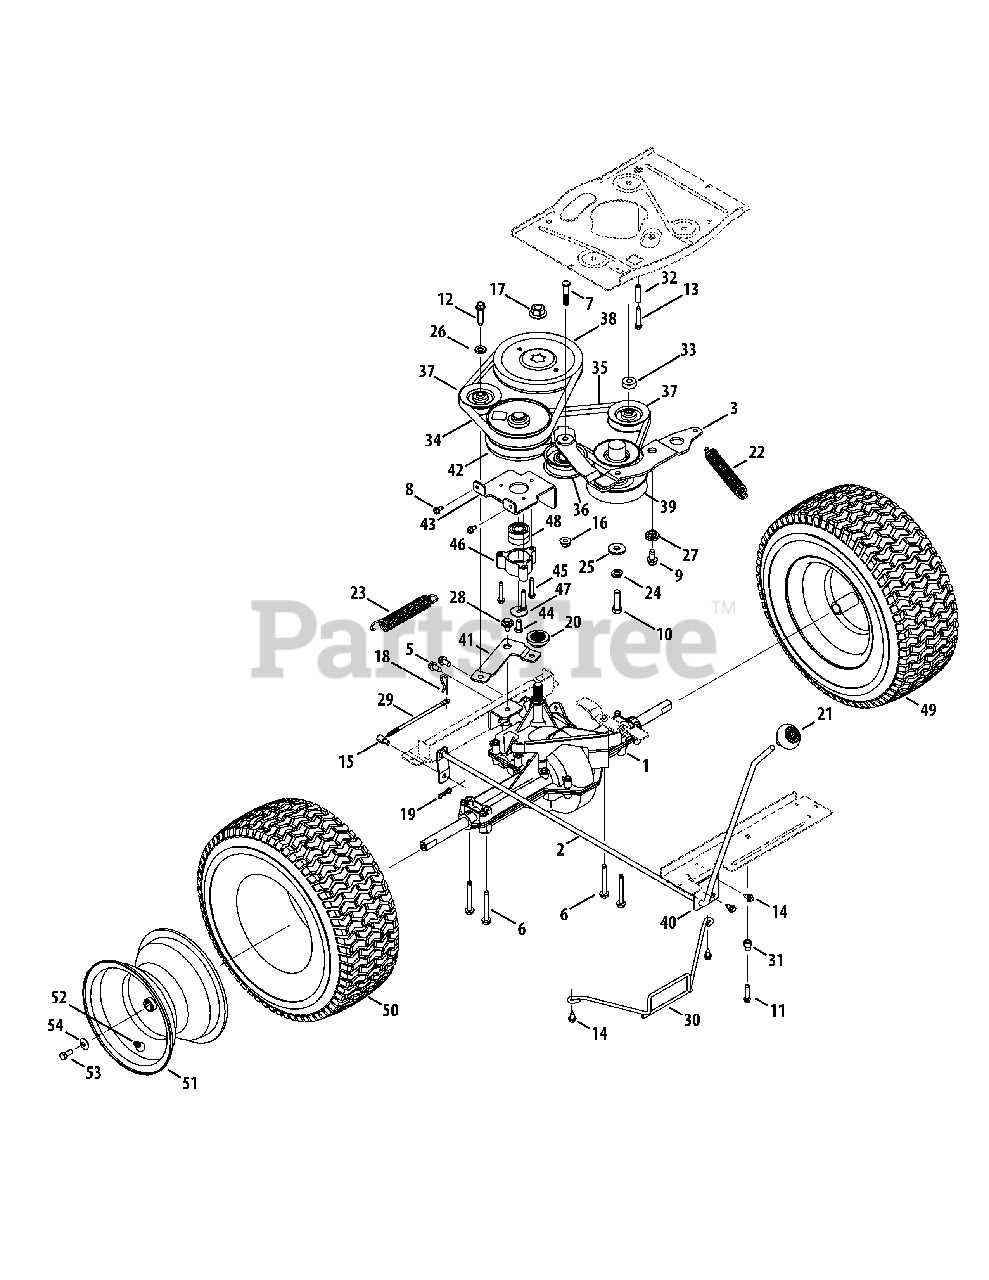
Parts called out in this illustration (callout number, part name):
1	Transmission Assembly
2	Shift Handle Assembly
5	Tap Screw, 5/16-18x.750
6	Tap Screw, 5/16-18x2.50
7	Hex Head Scew, 3/8-16x1.62
8	Tap Scew, 1/4-20x0.500
9	Tap Screw, 3/8-16x0.750
10	Hex Head Screw, 7/16-20x1.50
11	Tap Screw, 1/4-20x1.250
12	SEMS Tap Screw, 3/8-16x1.500
13	Tap Screw, 1/4-20x1.625
14	Tap Screw, 1/4-20 x .625
15	Adjustable Ferrule, 1/4-20 X 1.00
16	Flange Lock Nut, 3/8-16
17	Flange Nut, 9/16-18
18	Internal Cotter Pin, .125 Dia.
19	Bow-Tie Cotter Pin
20	Pulley Hub, 5/8 Spline
21	Shift Knob
22	Extension Spring, .94 Dia. X 6.74 Lg.
23	Extension Spring, .97 OD X 6.18
24	Split Lock Washer, 7/16
25	Flat Washer, .450X1.250X.164
26	Flat Washer, .407X.812X.135
27	Shoulder Spacer, 1.00 X .38 X .38
28	Shoulder Spacer, .560x.165x5/16-18
29	Shift Rod
30	Deck Belt Keeper, 30"
31	Stepped Spacer, .265 ID X .750
32	Spacer, .260 X .372 X 1.420
33	Spacer, .406 ID X 1.00 OD X .38
34	V-Belt, 5L:35.25
35	V-Belt, 5L:35.28
36	Flat Idler Pulley, 2.75 OD
37	V-Type Idler Pulley, 3.06
38	V-Type Pulley, 6.56
39	Engine Pulley, 4.46 / 3.39
40	Front Support Shift Bracket
41	Rear Idler Arm Bracket
42	Variable Speed Pulley Assembly
43	Variable Bracket
44	Hex Head Lock Screw, 5/16-24:.750
45	Tap Screw, 1/4-20:1.500
46	Bearing Cup
47	Flat Washer, .330x1.250x.060
48	Ball Bearing, 17 X 40 X 12
49	Complete Wheel Assembly
50	Tire, 16 x 6.5 x 8 Sq. Shoulder
51	Rim Assembly, 8.0 x 5.38
52	Air Valve
53	Hex Head Screw, 5/16-24, 7.50
54	Beveled Washer, .340 x .872 x .060
